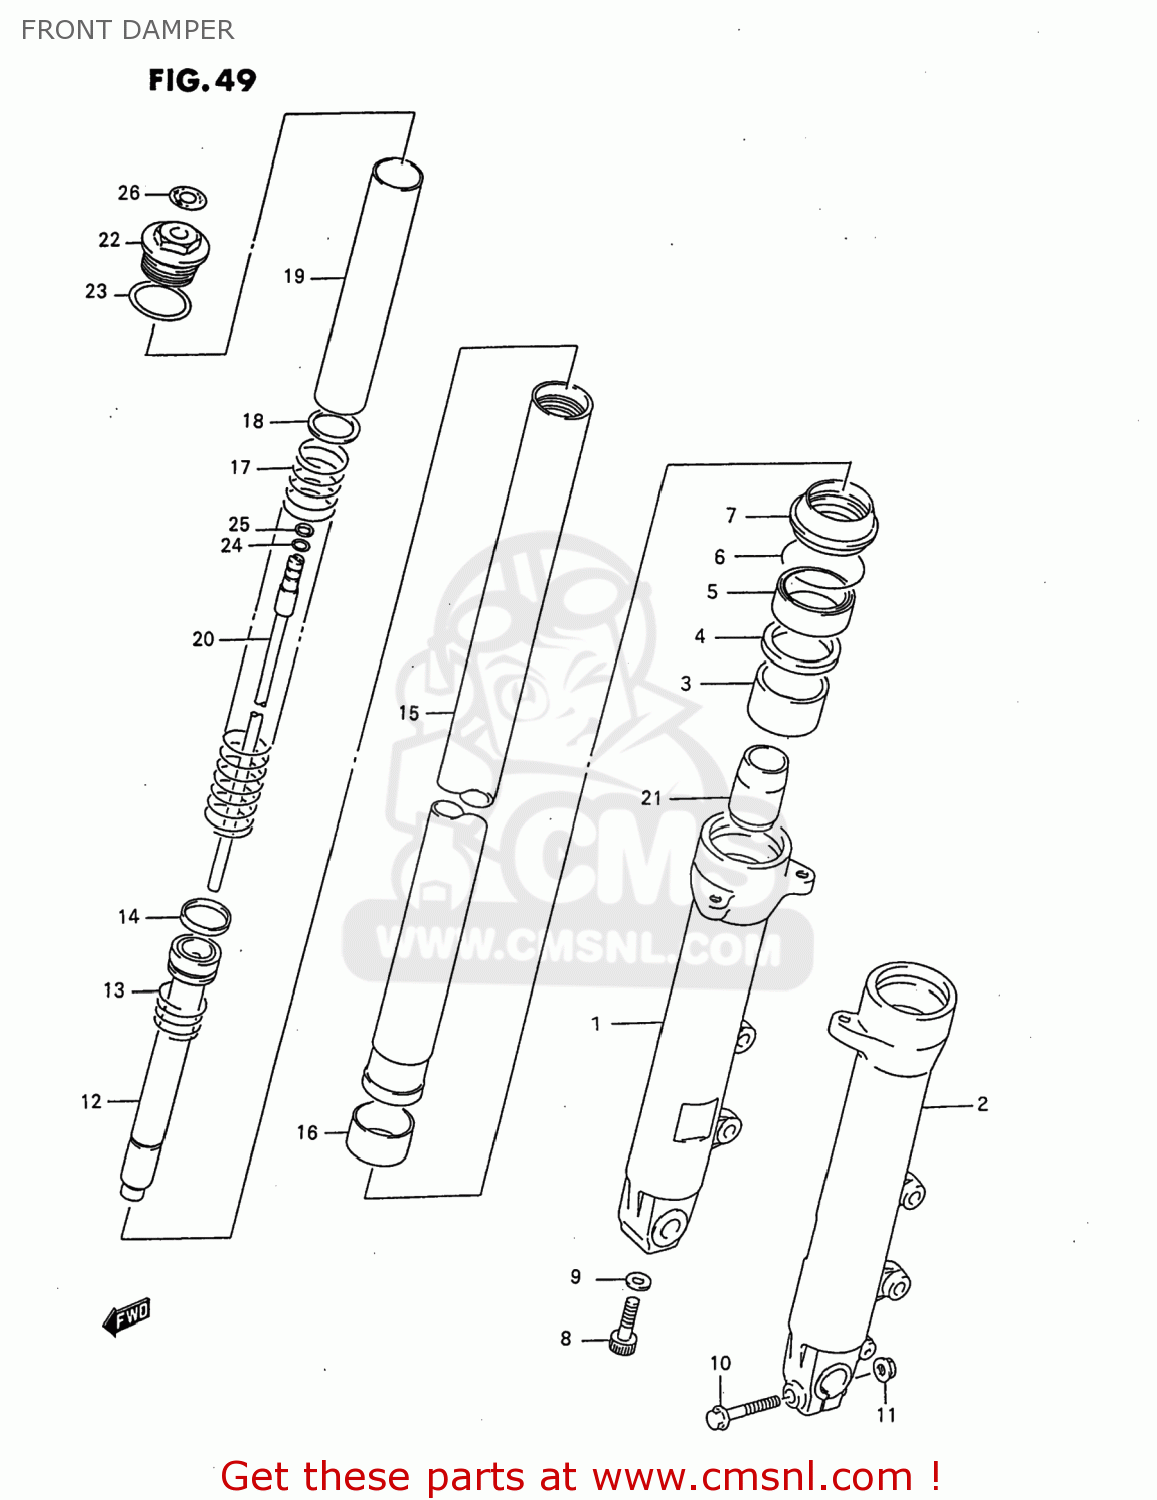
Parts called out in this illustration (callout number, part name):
1	TUBE,OUTER,RIGHT
2	TUBE,OUTER,L
3	BUSH,GUIDE
4	SPACER,SEAL
5	SEAL,OIL
6	CIRCLIP,FORK OIL SEAL
7	SEAL,DUST
8	BOLT(8X27)
9	GASKET (NAS)
10	BOLT
11	NUT
12	SEAT,UNDER
13	SPRING,REBOUND
14	RING,PISTON
15	TUBE,INNER
16	BUSH,SLIDE
17	SPRING,FRONT
18	JOINT,SPRING
19	SPACER,SPRING
20	ROD,INNER
21	PIECE,OIL LOCK
22	BOLT,FORK
23	O RING
24	O RING(D:1.9,ID:5.7)
25	RING,STOPPER(ID:6.1,D:0.6)
26	LABEL,S-H
